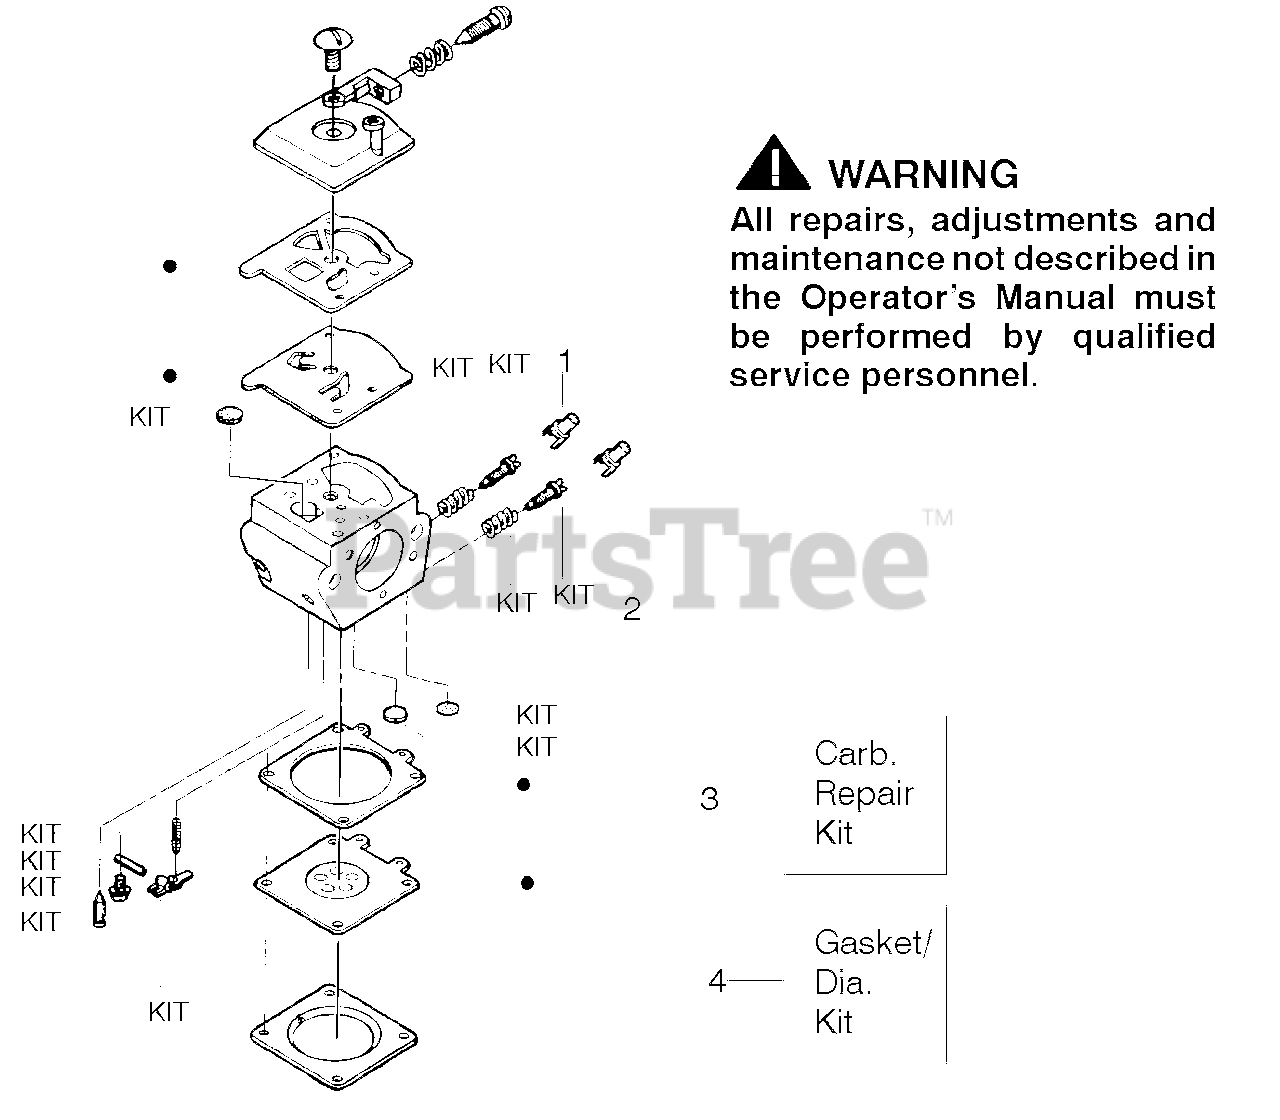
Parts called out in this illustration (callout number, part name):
1	Limiter Cap-High (brown)
2	Limiter Cap-Low (tan)
3	Carburetor Repair Kit Walbro (WT324)
4	Gasket Diaphragm Kit Walbro (WT324)
